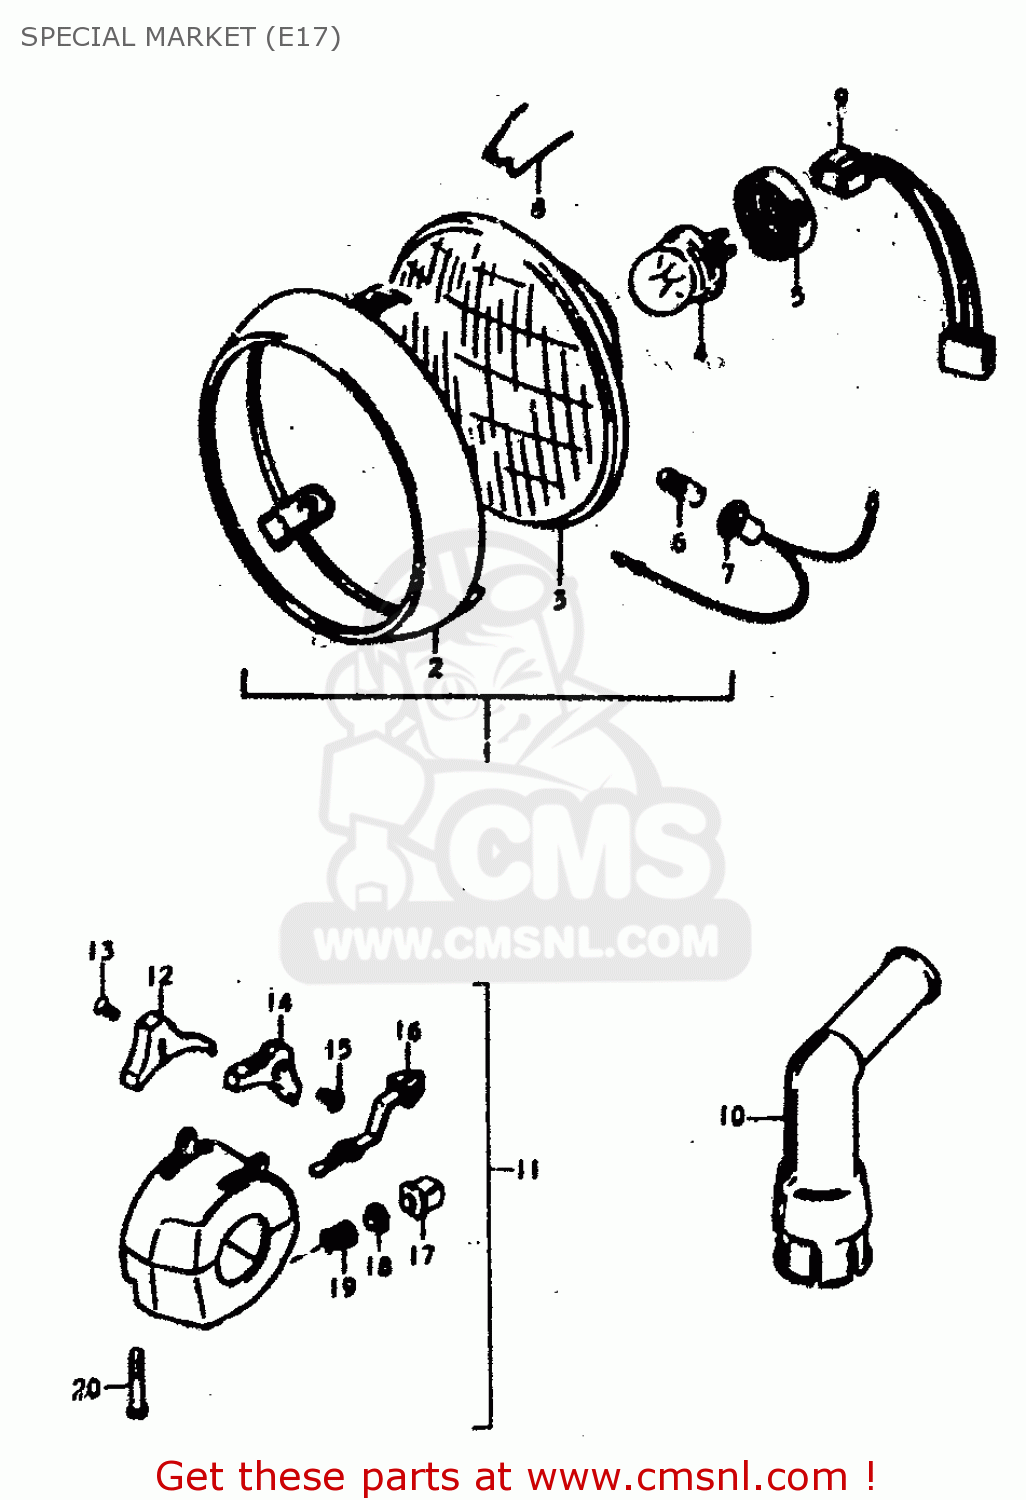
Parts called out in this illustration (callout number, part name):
1	HEADLAMP ASSY
2	RIM
3	UNIT
4	BULB(12V45/40W)
5	SETTER,BULB
6	BULB(12V4W)
7	SOCKET
8	SPRING,HEAD LA
9	LEAD WIRE,HEADLAMP
10	CAP, SPARK PLUG (S)
11	SWITCH ASSY,HANDLE LH
12	KNOB,LIGHTING SWITCH
13	SCREW
14	KNOB,DIMMER SWITCH
15	SCREW
16	KNOB,TURNSIGNAL
17	BUTTON,HORN
18	CONTACT
19	SPRING
20	SCREW
